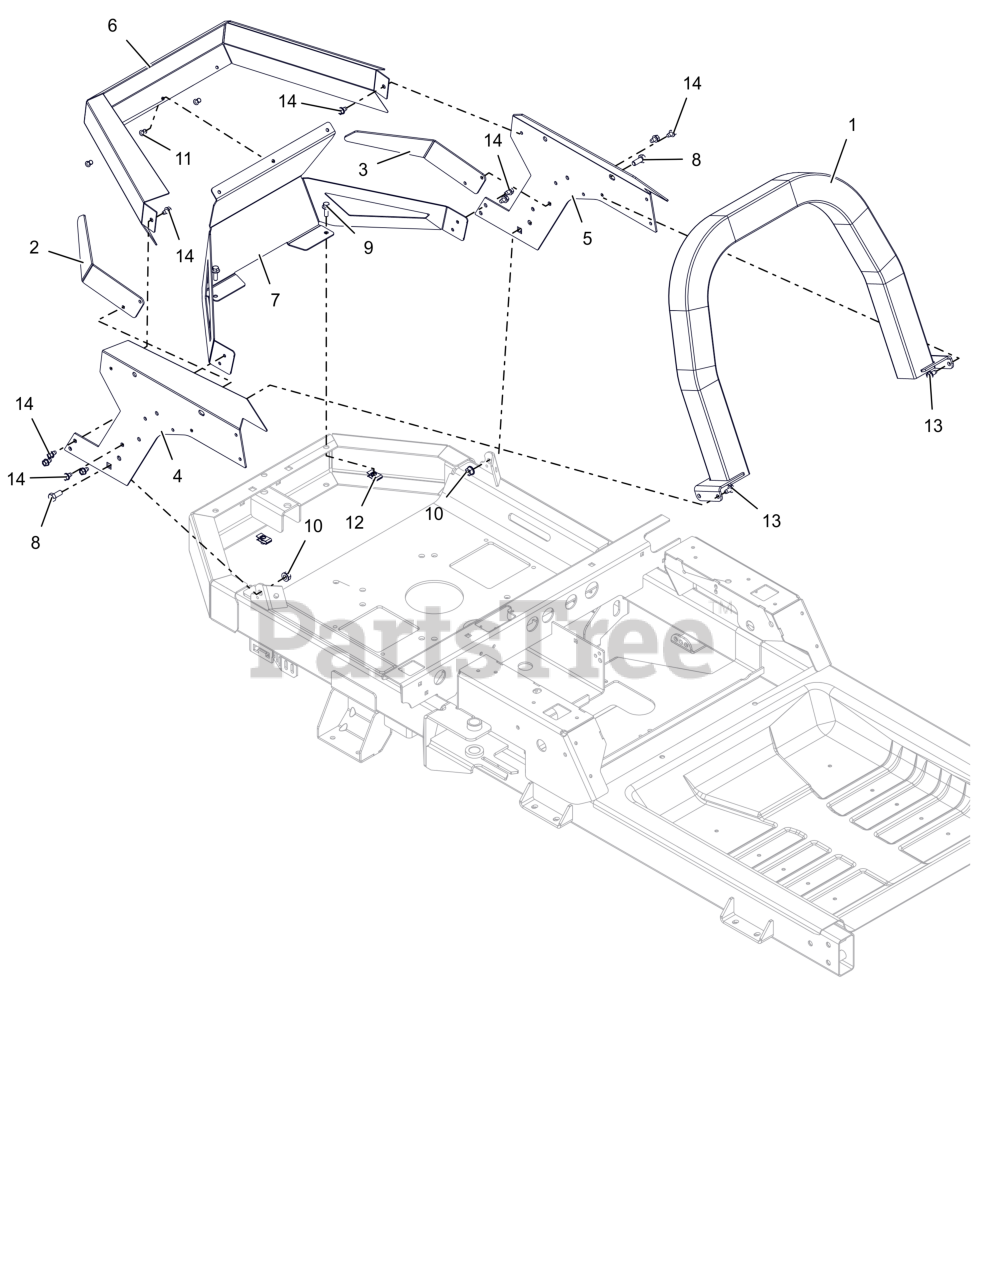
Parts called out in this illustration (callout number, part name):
1	ENGINE-TOP GUARD (ORANGE)
2	SHIELD, RH, ENGINE GUARD VALVE
3	SHIELD, LH, ENGINE GUARD VALVE
4	PANEL, RIGHT REAR FENDER MOUNT (ORANGE)
5	PANEL, LH REAR FENDER MOUNT (ORANGE)
6	GUARD, ENGINE WRAP (ORANGE)
7	GUARD, ENGINE -BOTTOM (BLACK)
8	BLT,HEX .31-18X.75 G5 ZCC
9	BLT,HEX-FLG .25-20X.75 G5 BFP
10	NUT-LK-TOP-FLG .312-18 GF ZCC
11	RIVET, #66 STEEL POP PD BLACK
12	NUT-RTNR .25-20X.56
13	SCR-TAP .25-20X.50 HWH ZCC
14	SCR,TAP .25-20X.375 HWH TR ZCC
